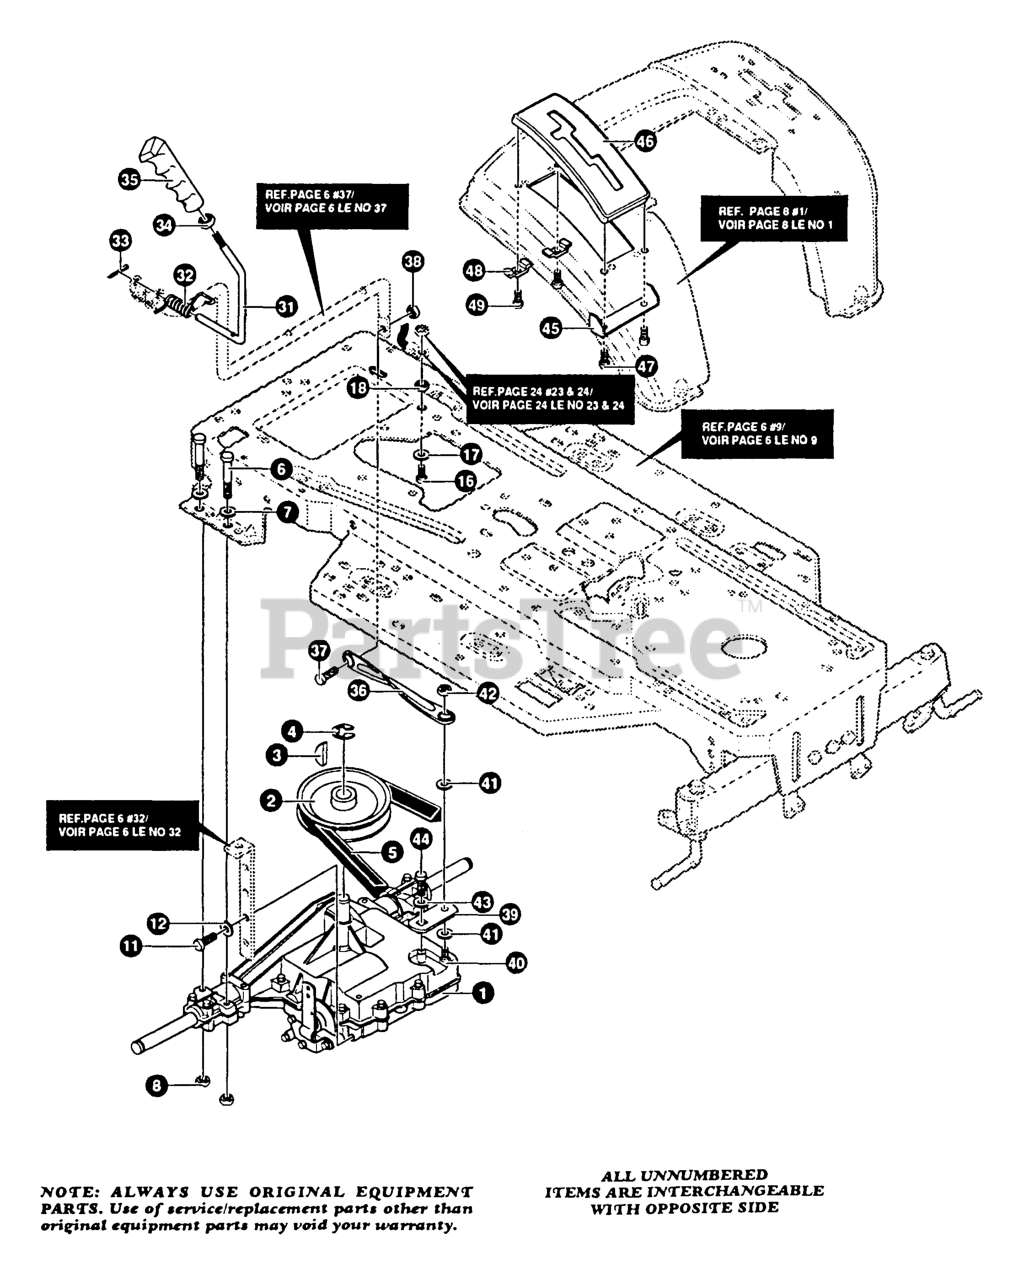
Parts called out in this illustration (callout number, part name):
1	TRANSAXLE **
4	RING, RETEX
7	WASHER
11	SCREW
12	WASHER
16	SCREW
17	WASHER
31	LEVER, SHIFT
32	SPRING, TORSION
33	PIN, COTTER
36	LINK, TIE ROD SHIFT
38	NUT
39	BRACKET, SHIFT
41	WASHER
42	NUT
44	SCREW
45	BRACKET COVER
46	COVER, PLASTIC
48	CLAMP, SPRING
